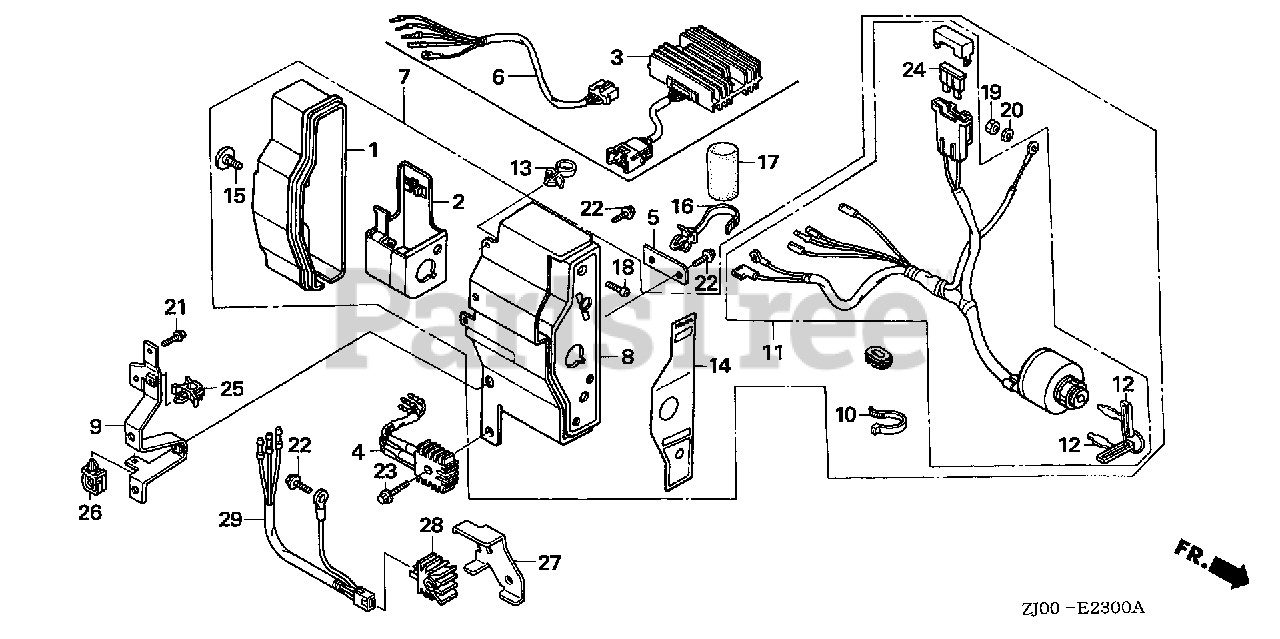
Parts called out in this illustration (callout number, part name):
1	CASE, CONTROL
2	BRACKET, CASE MOUNTING
3	RECTIFIER ASSY., REGULATOR (20A)
5	BRACKET, WIRE HARNESS CLIP
6	SUB-WIRE HARNESS ASSY.
7	BOX ASSY., CONTROL
8	PANEL, CONTROL
9	STAY, CONTROL BOX
11	SWITCH ASSY., COMBINATION
12	KEY (HONDALOCK)
13	HOLDER, STOP SWITCH WIRE
14	MARK, CONTROL BOX (EXTERNAL-REGULATOR)
15	SCREW, SPECIAL (6X12)
16	BAND, WIRE HARNESS (150MM) (BLUE)
17	TUBE, CORD (30MM)
18	SCREW, PAN (4X12)
19	NUT, HEX. (4MM)
20	WASHER, SPRING (4MM)
21	BOLT, FLANGE (6X10)
24	FUSE, BLADE (25A)
25	CLIP, WIRE HARNESS
26	CLIP, WIRE HARNESS (BLACK)
